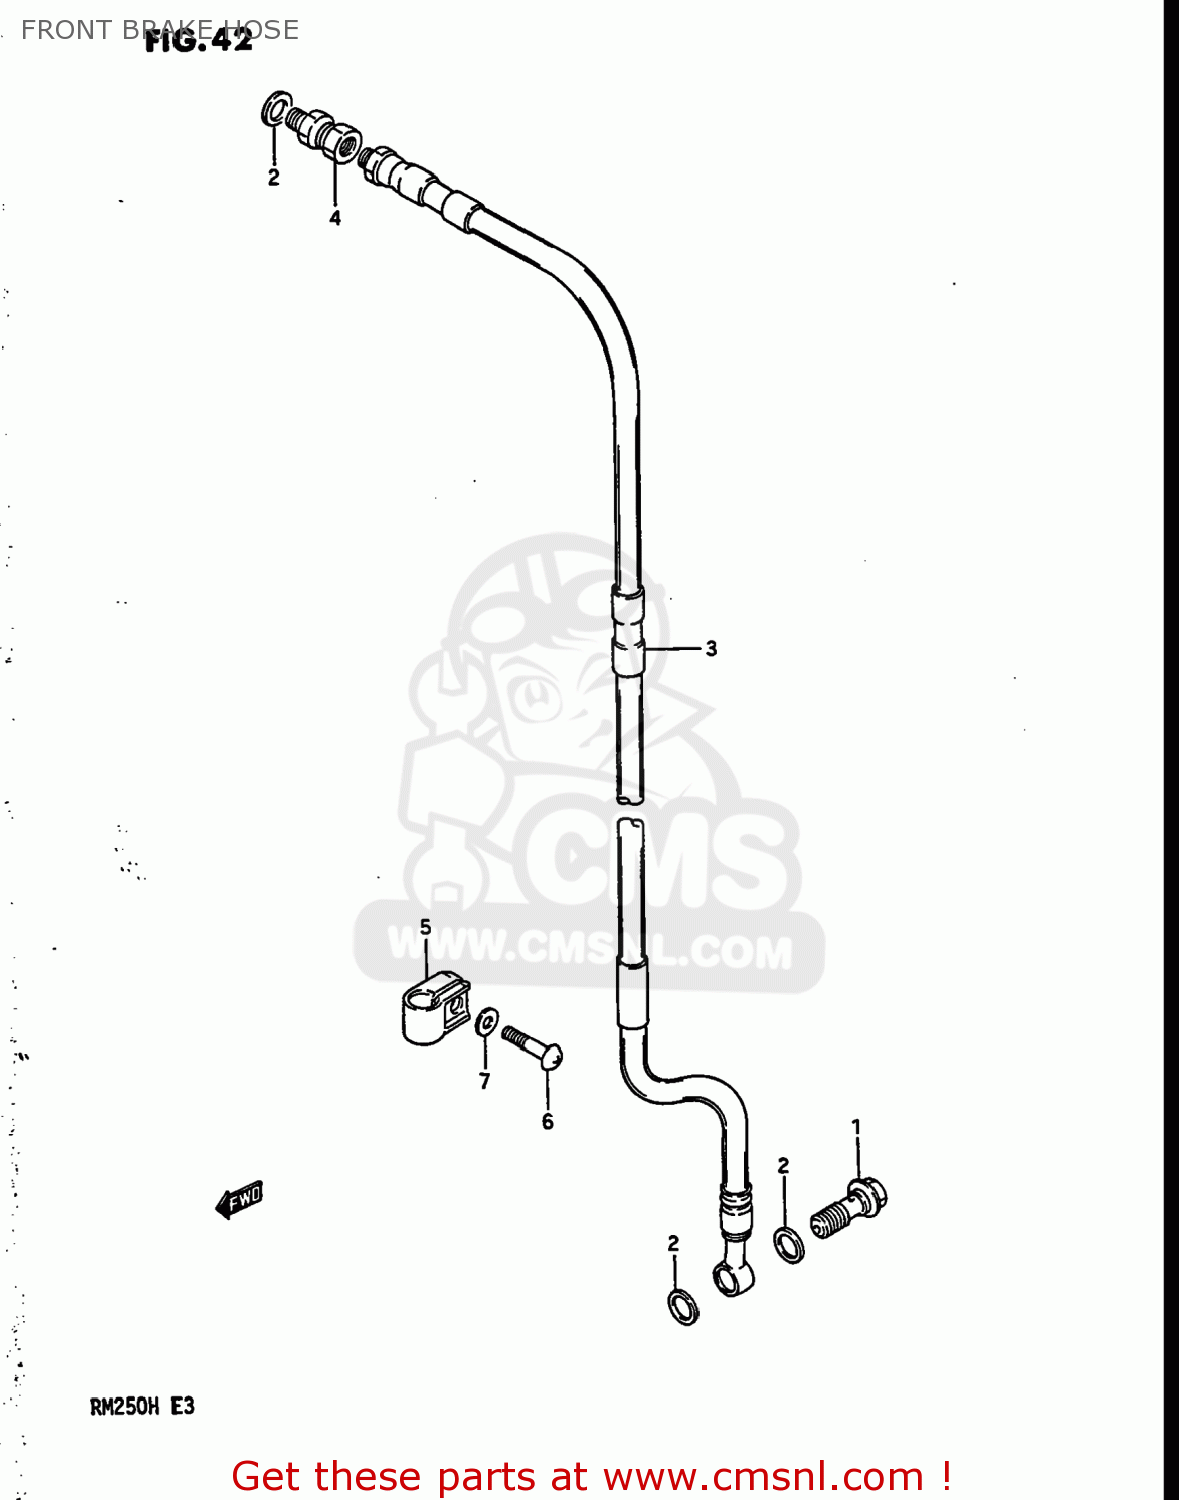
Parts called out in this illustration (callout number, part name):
1	BOLT UNION
2	WASHER(10X15X1.5)
3	HOSE,FRONT BRAKE
4	ADAPTER,BRAKE HOSE
5	CLAMP,FRONT BRAKE HOSE
6	SCREW
7	WASHER
